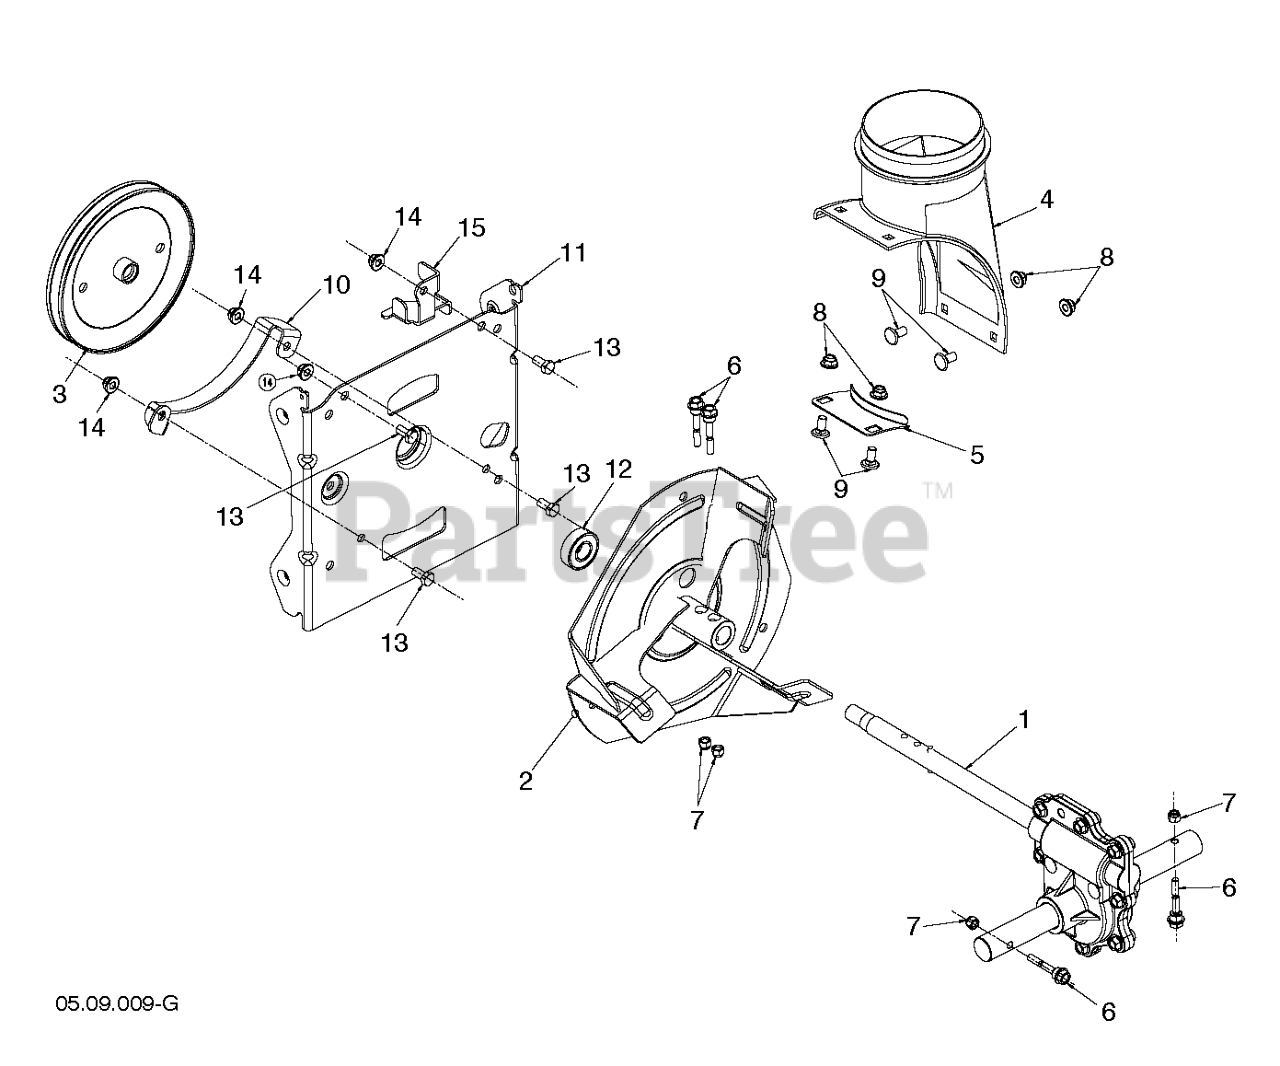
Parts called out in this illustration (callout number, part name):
1	GEARBOX.AUGER.
2	IMPELLER.STEEL.SNOW.BLACK
3	PULLEY SCREW ON 7.3 5/8
4	CHUTE.DISCHARGE.BASE
5	BRACKET, CORNER DISCHARGE
6	BOLT.1/4-20 X 1-13/16 SHEAR
7	LOCKNUT.NYLOC.1/4-20
8	NUT HEX FLG NYLOCK BLK 5_16-1
9	BOLT CARR WAFER BLK 5_16-18 X
10	BRACKET.BELT.KEEPER.LOWER.BLAC
11	BRACKET.AUG.HOUSING.INTER.BLAC
13	BOLT, HEX HEAD 5/16-18
14	NUTNYLOK.FLRANGE.5/16-18
15	GUIDE.LOWER.AUGER.BELT.479
